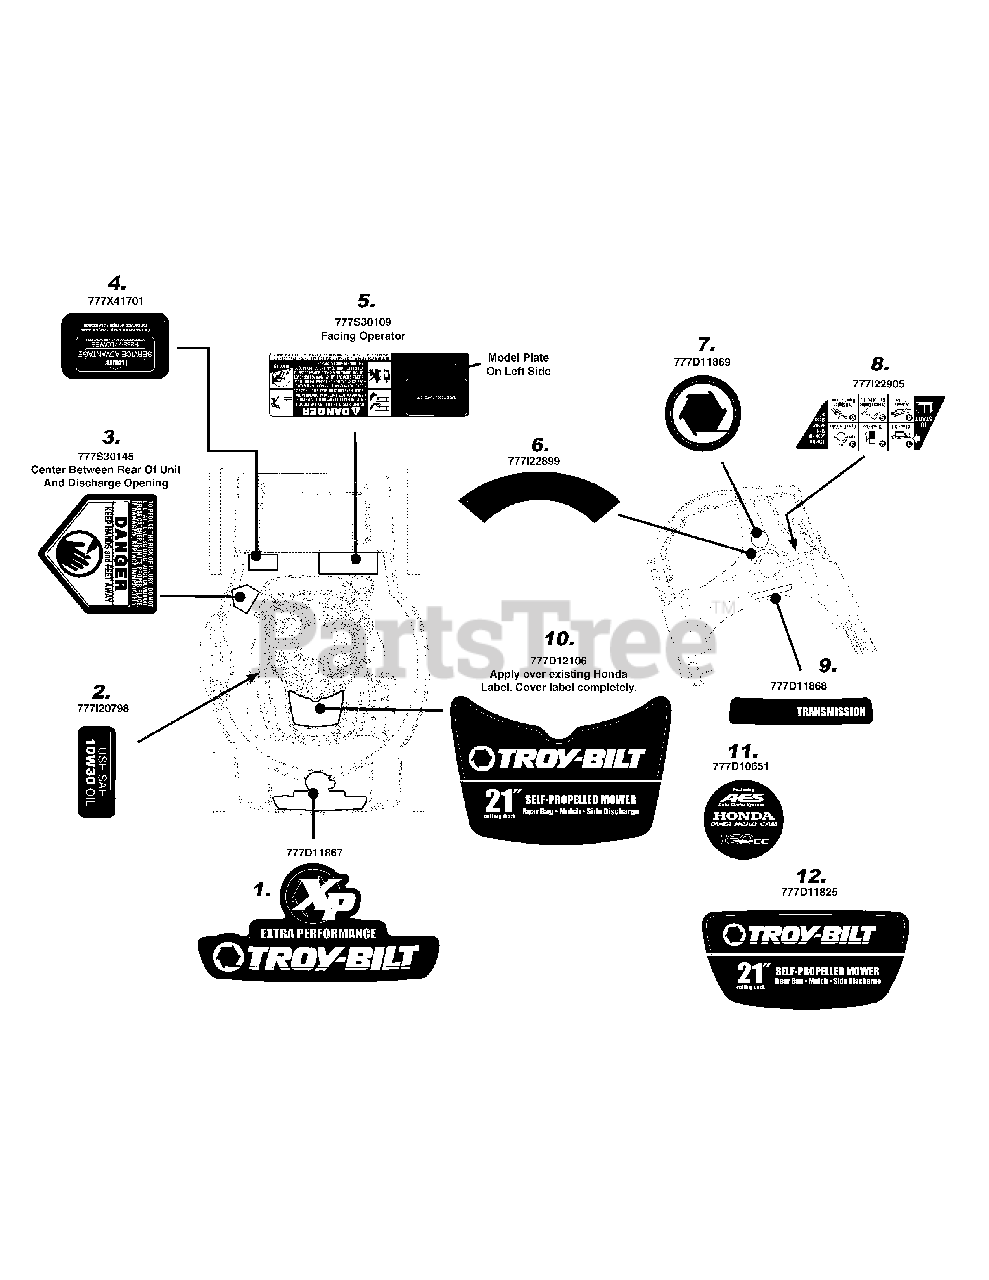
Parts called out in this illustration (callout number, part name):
1	LABEL-MOWER 800 XP TROY
2	LBL:MWR:SRHD:HONDA OIL CAPCTY
3	LABEL
4	LBL:LOWES SERVICE ADVANTAGE
5	LBL:MWR:DNGR:STRGHT:W/O 1-800
6	LABEL-MOWER XP HANDLE SELECT
7	LABEL-EMBOSSED TROYBILT
8	LABEL-MOWER HANDLE HONDA
9	LABEL-MOWER XP HANDLE SELECT TROY
10	LABEL-MOWER SHROUD TROY
11	LBL:ENG SPNR:PWRD BY HONDA/ENG
12	LABEL-MOWER SHROUD TROY SP
